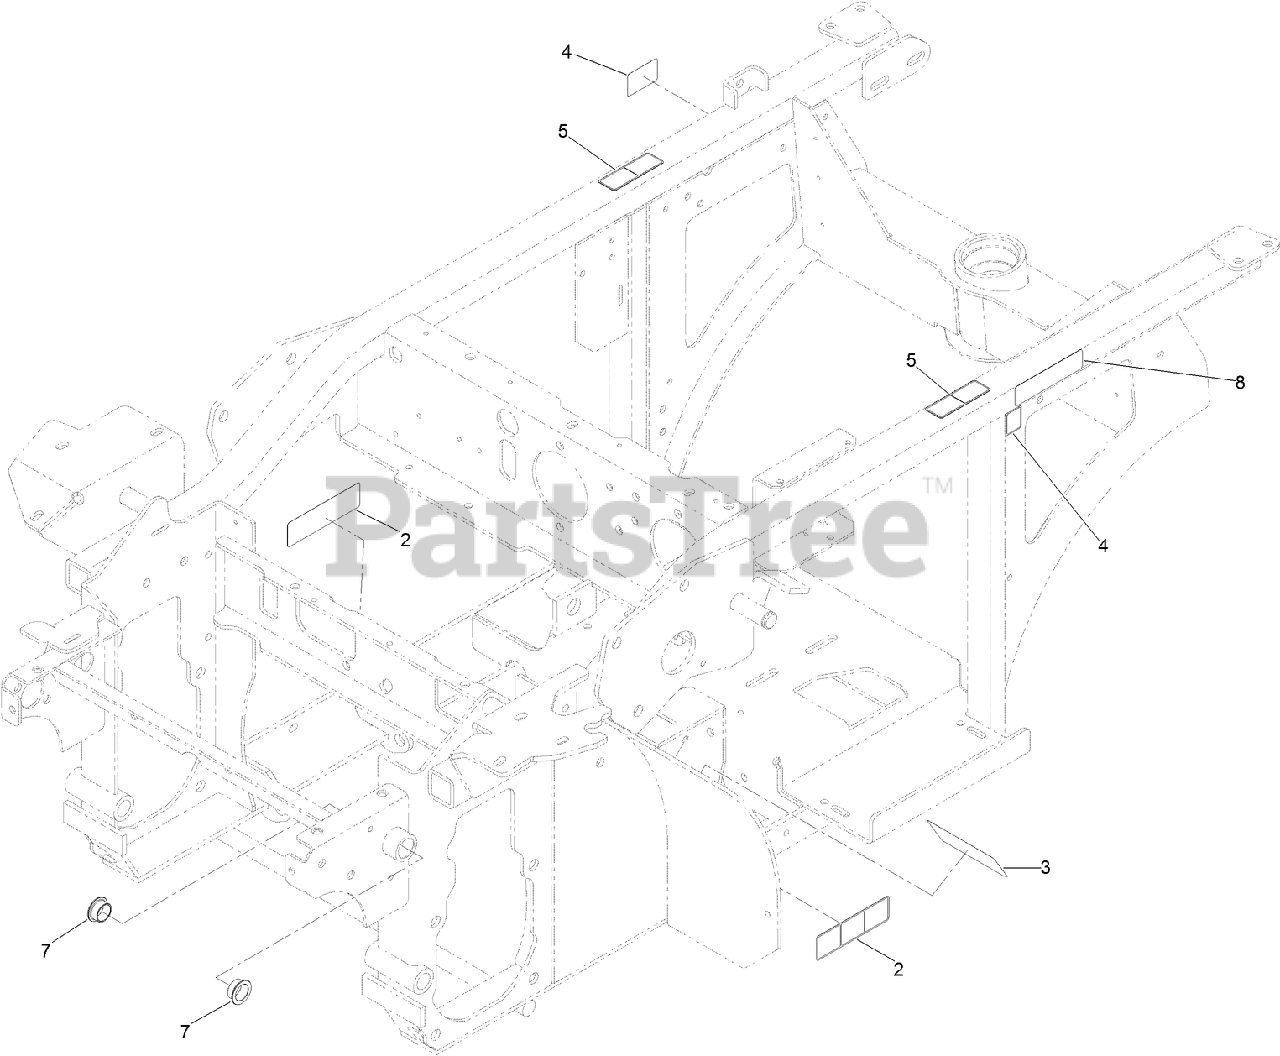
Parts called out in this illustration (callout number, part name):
2	DECAL-COVER, MISSING
3	DECAL-ADJUSTMENT, CLUTCH
4	DECAL-WARNING
5	DECAL-WARNING, PINCH POINT
7	BUSHING-BRONZE
8	DECAL-ARRESTOR, SPARK
